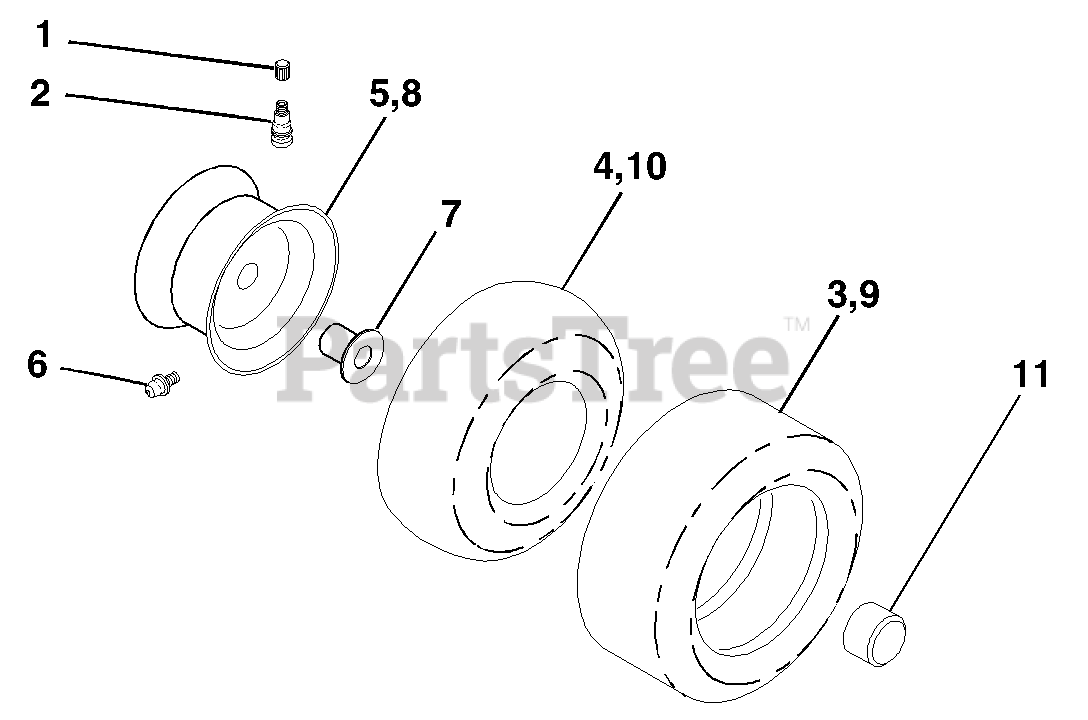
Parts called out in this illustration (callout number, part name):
1	Cap Valve Tire
2	Stem Valve
3	Tire Front
4	Tube Front
5	Rim Asm 6" front
6	Fitting Grease
7	Bearing Flange
8	Rim Asm 12" rear
9	Tire R 23 x 9.5-12 C Service
10	Tube Rear
11	Cap Axle Blk 1 50 X 1 00
